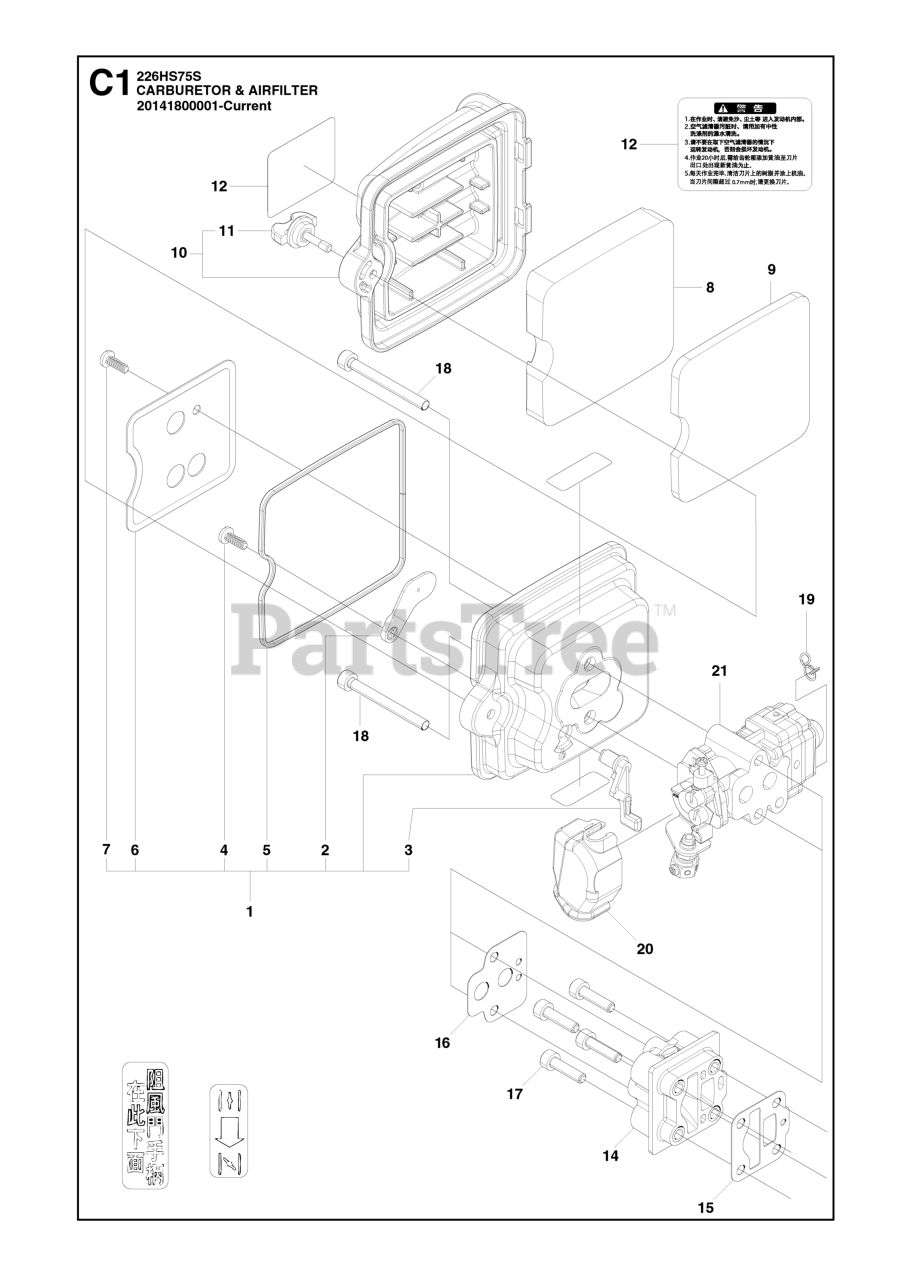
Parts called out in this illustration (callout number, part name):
2	PLATE.CHOKE
3	LEVER CHOKE
8	FILTER FOAM
10	COVER ASSY
12	LABEL
15	INSULATOR GASKET(R-848F0814B0)
16	GASKET, CARB (RPLS T155113131)
21	CARBURETTOR ASSY
